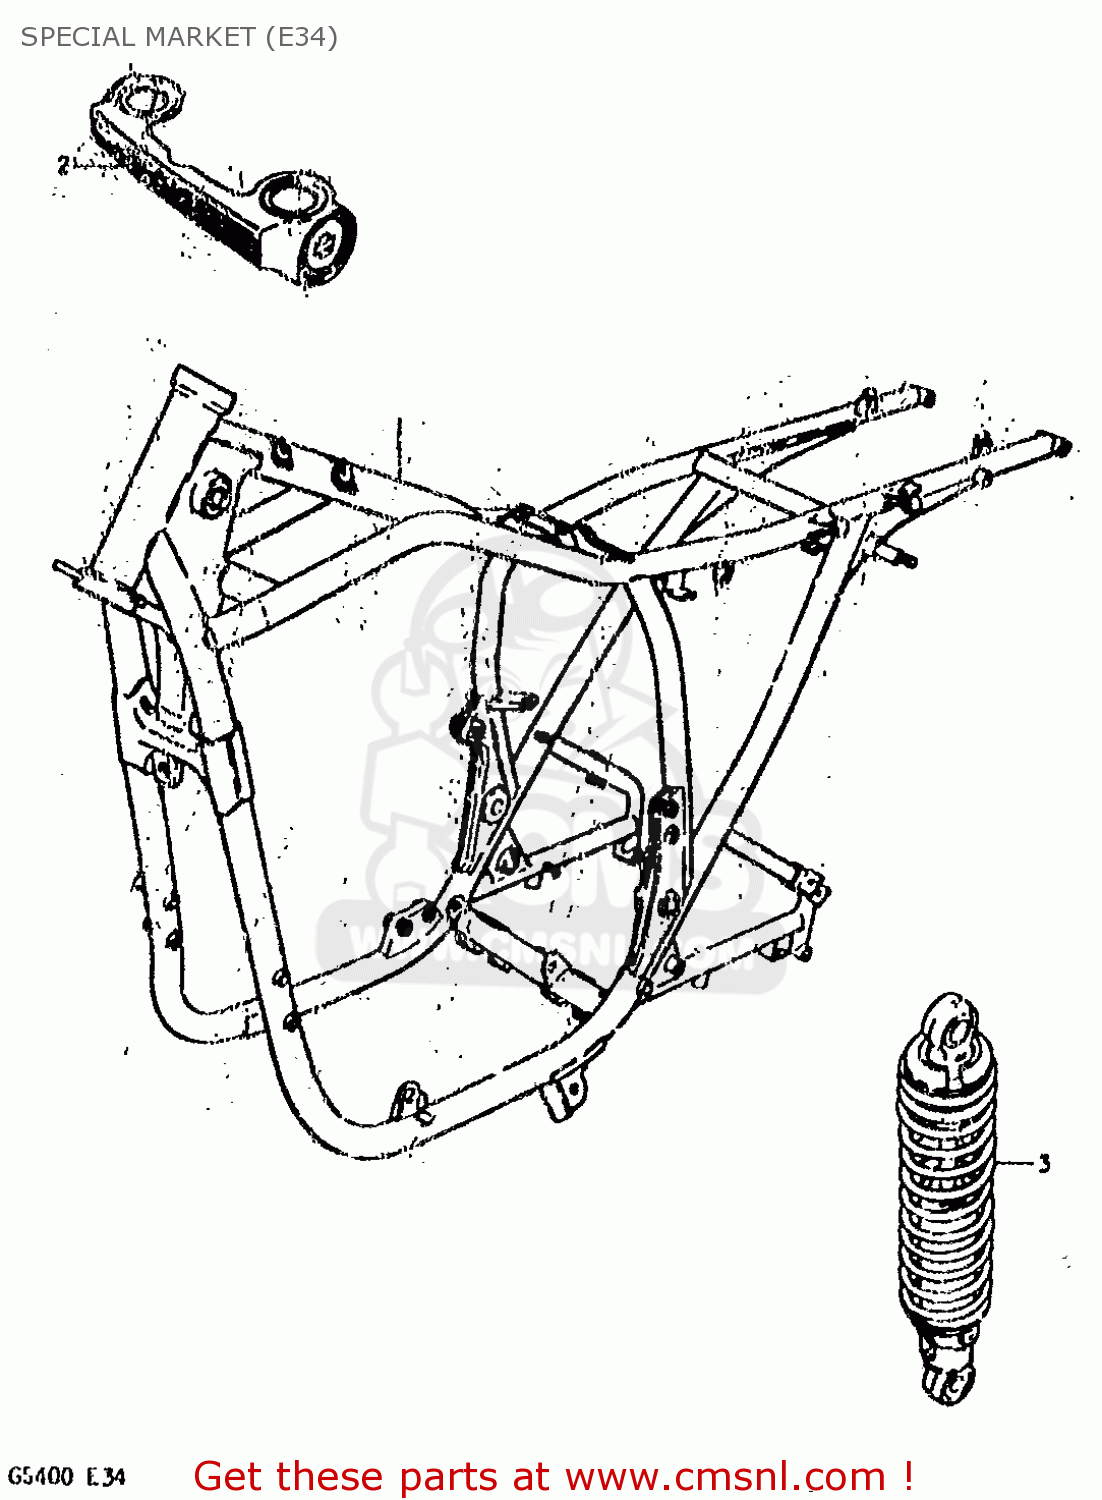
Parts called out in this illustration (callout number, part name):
1	FRAME
2	COVER, FRONT FORK
3	SHOCK ABSORBER, REAR
